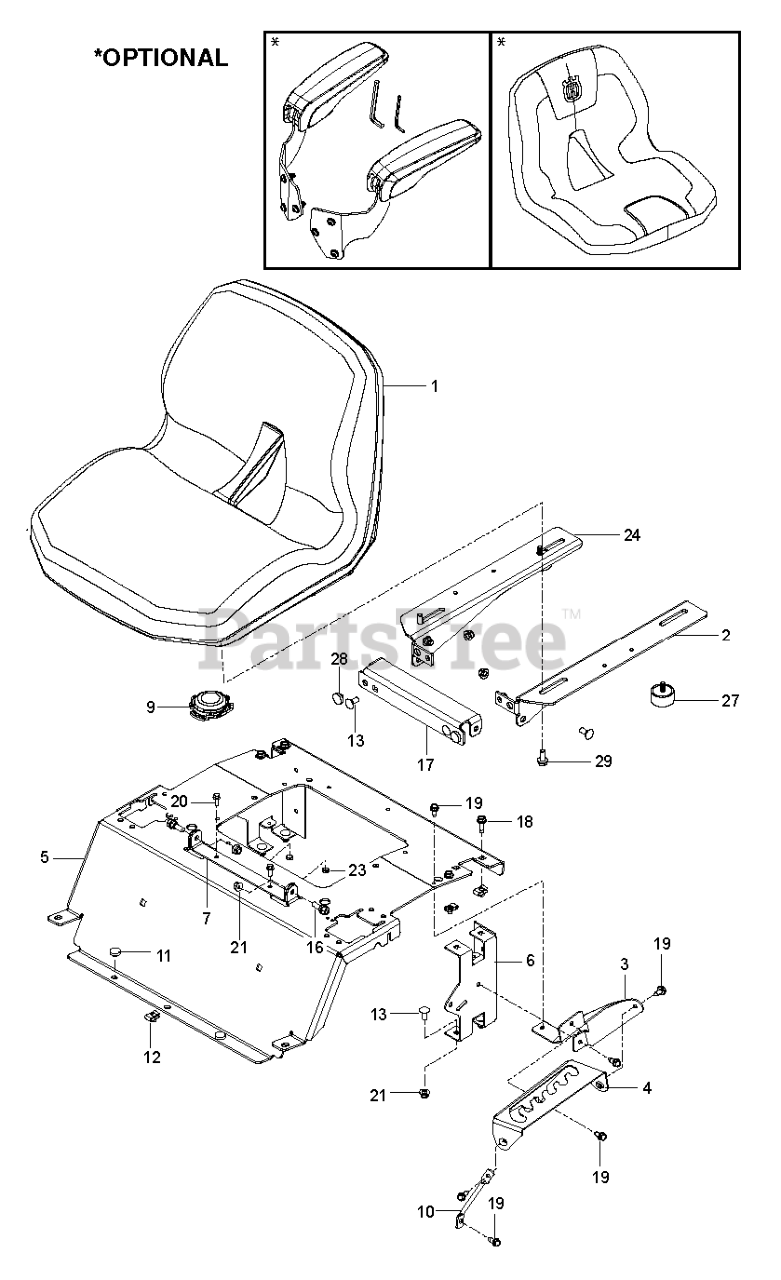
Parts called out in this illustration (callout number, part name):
2	BRACKET SEAT PAN LEFT BLACK X4
3	PLATE.SUPPORT.DECK.LIFT.X431
4	PLATE.DECK.LIFT.X431
5	SUPPORT.SEAT.RZ.HUSQ.ORANGE
6	SUPPORT REAR SEAT BLACK
7	BRACKET.SEAT.REINF.X668
9	SWITCH.SEAT.DP W/RAMPS
10	SUPPORT.LEG.DECK.LIFT
11	GROMMET.BUMPER
12	U-CLIP 5/16-18 NUT RETAINER
13	BOLT 5/16C X 3/4" CARRIAGE
16	BOLT, SHOULDER
17	BRACKET FRONT SEAT PAN BLACK X
18	SCREW.THDROL.5/16-18X3/4.TTY
19	BOLT.5/16HEX.WHS.HD
20	SCREW.FLG.LOCKING.1/4-20X.75
21	5/16-18 NYLOC FLANGE NUT
23	NUT
24	BRACKET SEAT PAN RIGHT BLACK X
27	BUMPER 5/16-18 CLEAR ZINC
28	GROMMET, BUMPER
29	HHFS 5/16-18 X 3/4
